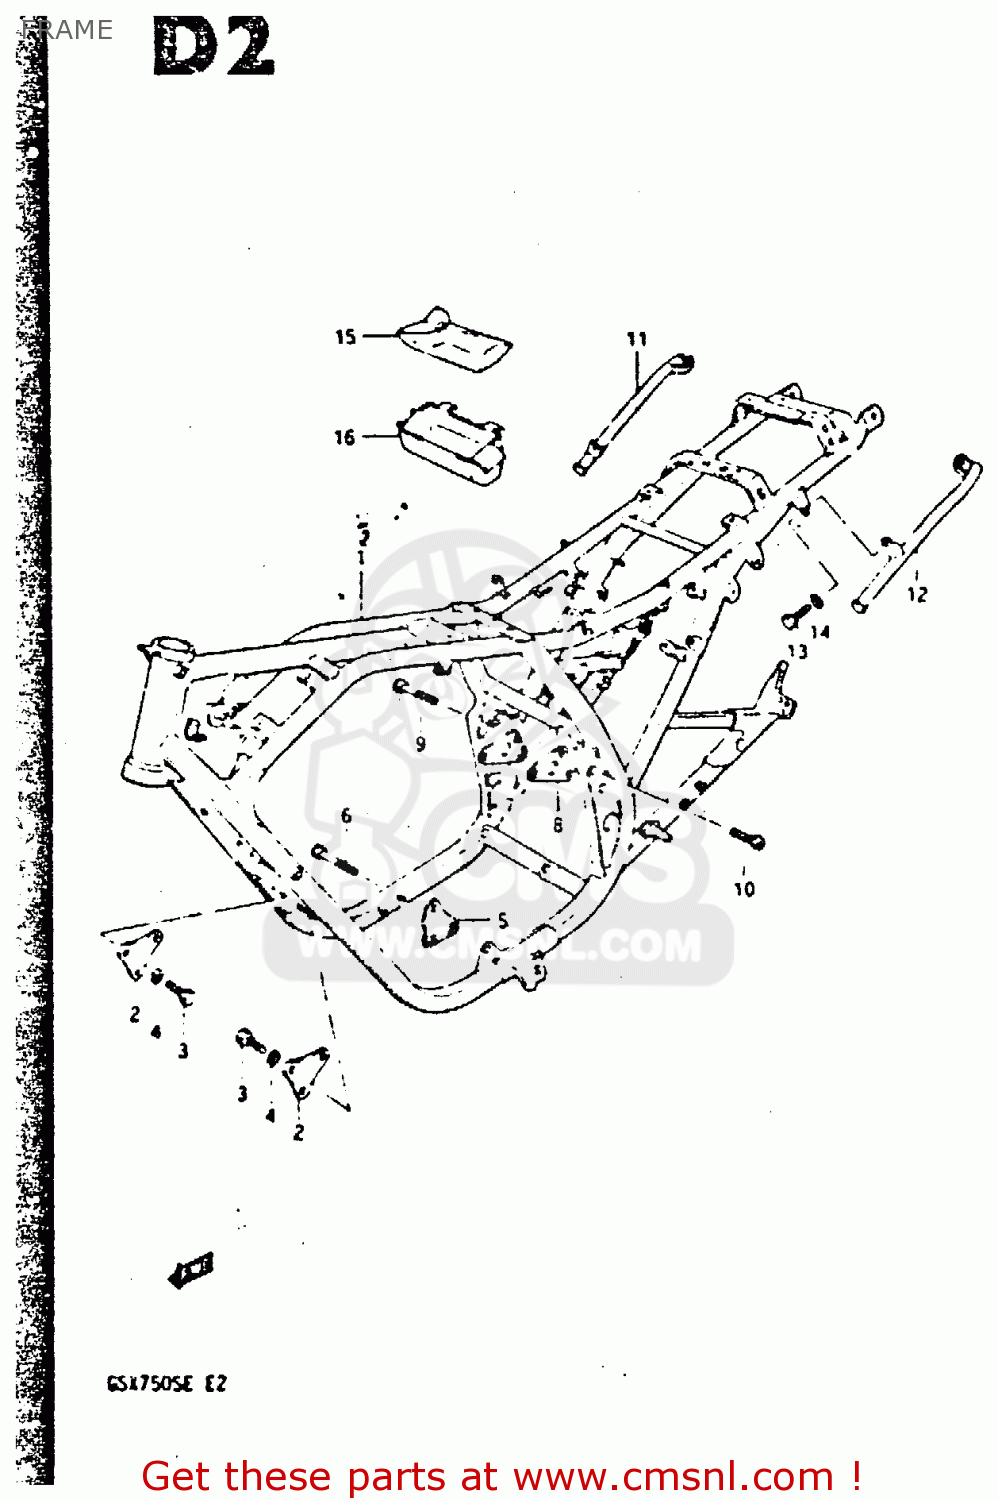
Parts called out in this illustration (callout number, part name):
1	FRAME (GOLD)
2	PLATE,ENGINE MOUNTING NO
3	BOLT
4	WASHER,LOCK,8.
5	PLATE,ENGINE MOUNTING NO
6	BOLT
7	PLATE,ENGINE MOUNTING NO
8	PLATE,ENGINE MOUNTING NO
9	BOLT 8X35
10	BOLT
11	GRIP, FRAME HANDLE RH
12	GRIP, FRAME HANDLE LH
13	BOLT
14	LOCK WASHER
15	TOOL SET
16	HOLDER,TOOL
